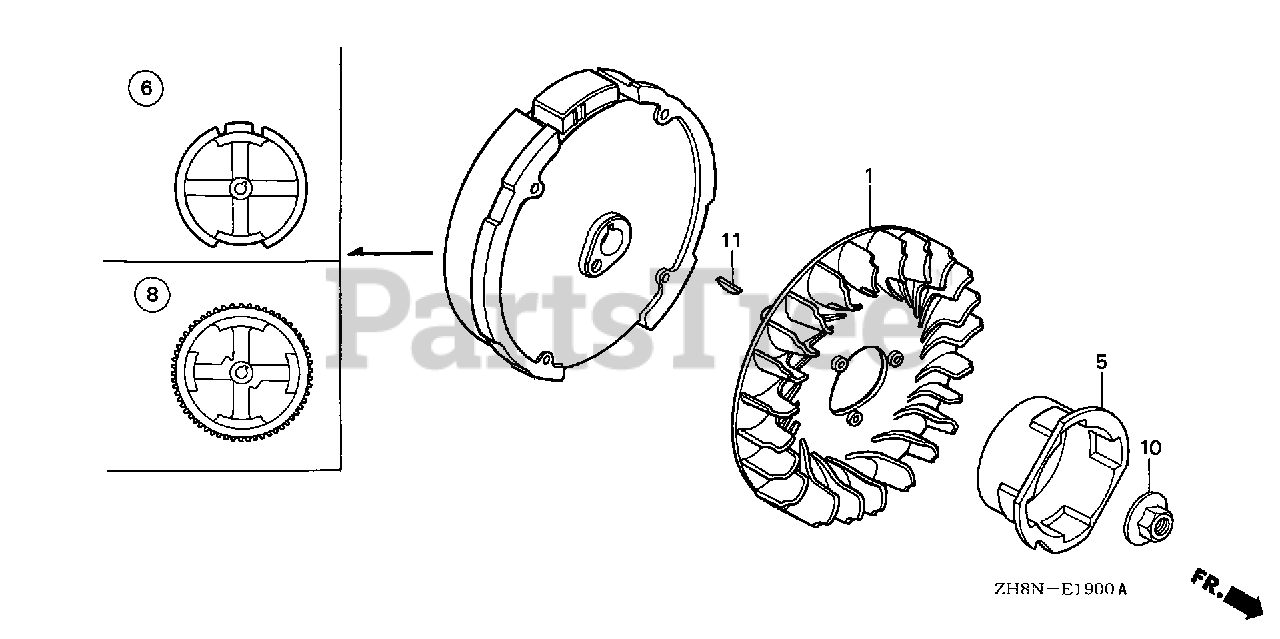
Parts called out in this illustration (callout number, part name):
1	FAN, COOLING
5	PULLEY, STARTER
6	FLYWHEEL
10	NUT, SPECIAL (14MM)
11	KEY, SPECIAL WOODRUFF (25X18)
